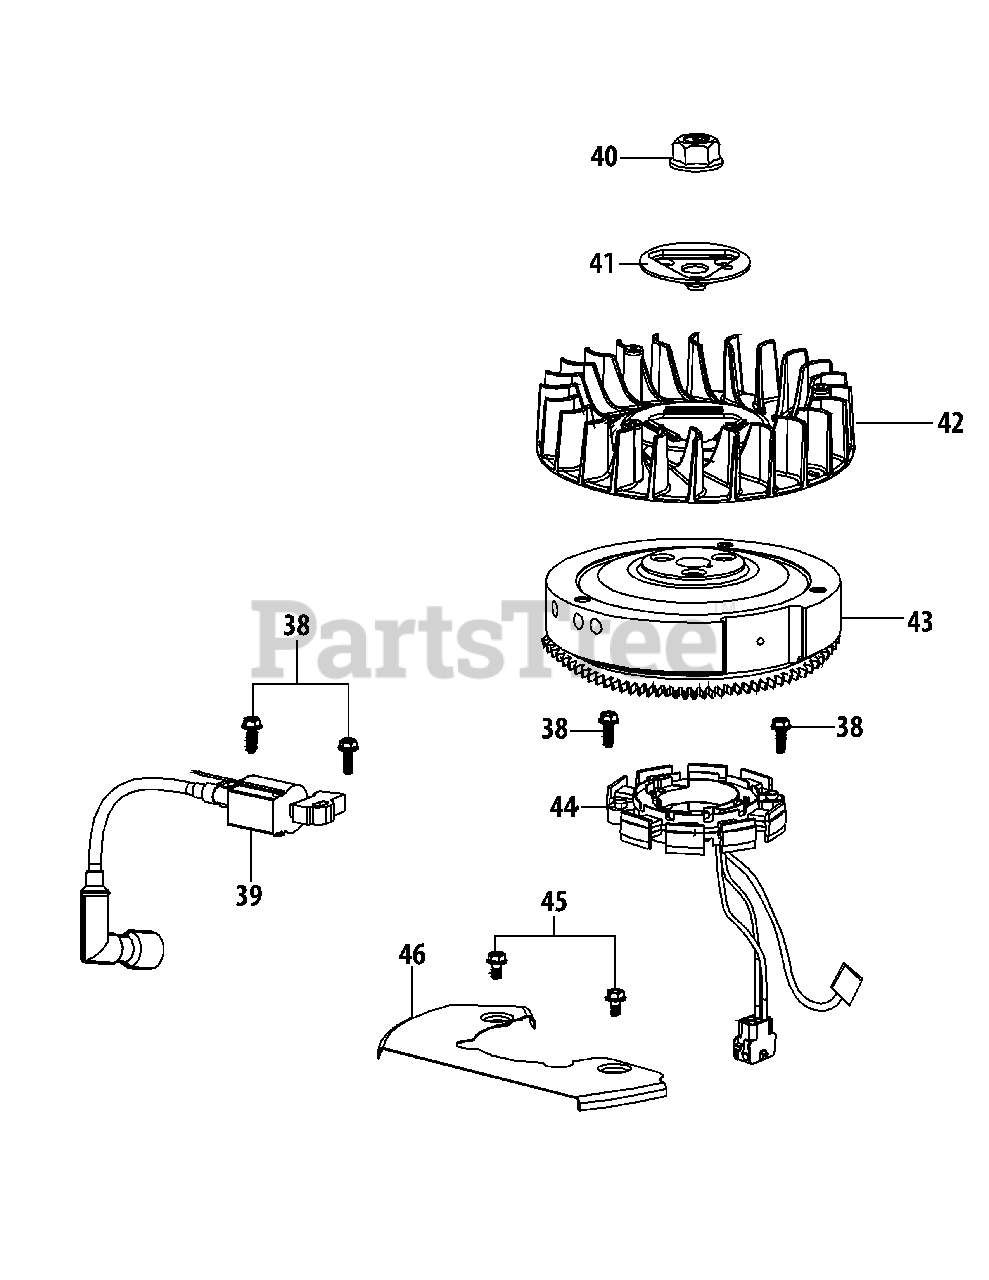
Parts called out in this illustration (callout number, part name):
38	Bolt M6×28
39	Ignition Coil Assembly
40	Flywheel Nut M16×1.5
42	Cooling Fan
44	Coil Assy.,Charge
45	Bolt M6×10
